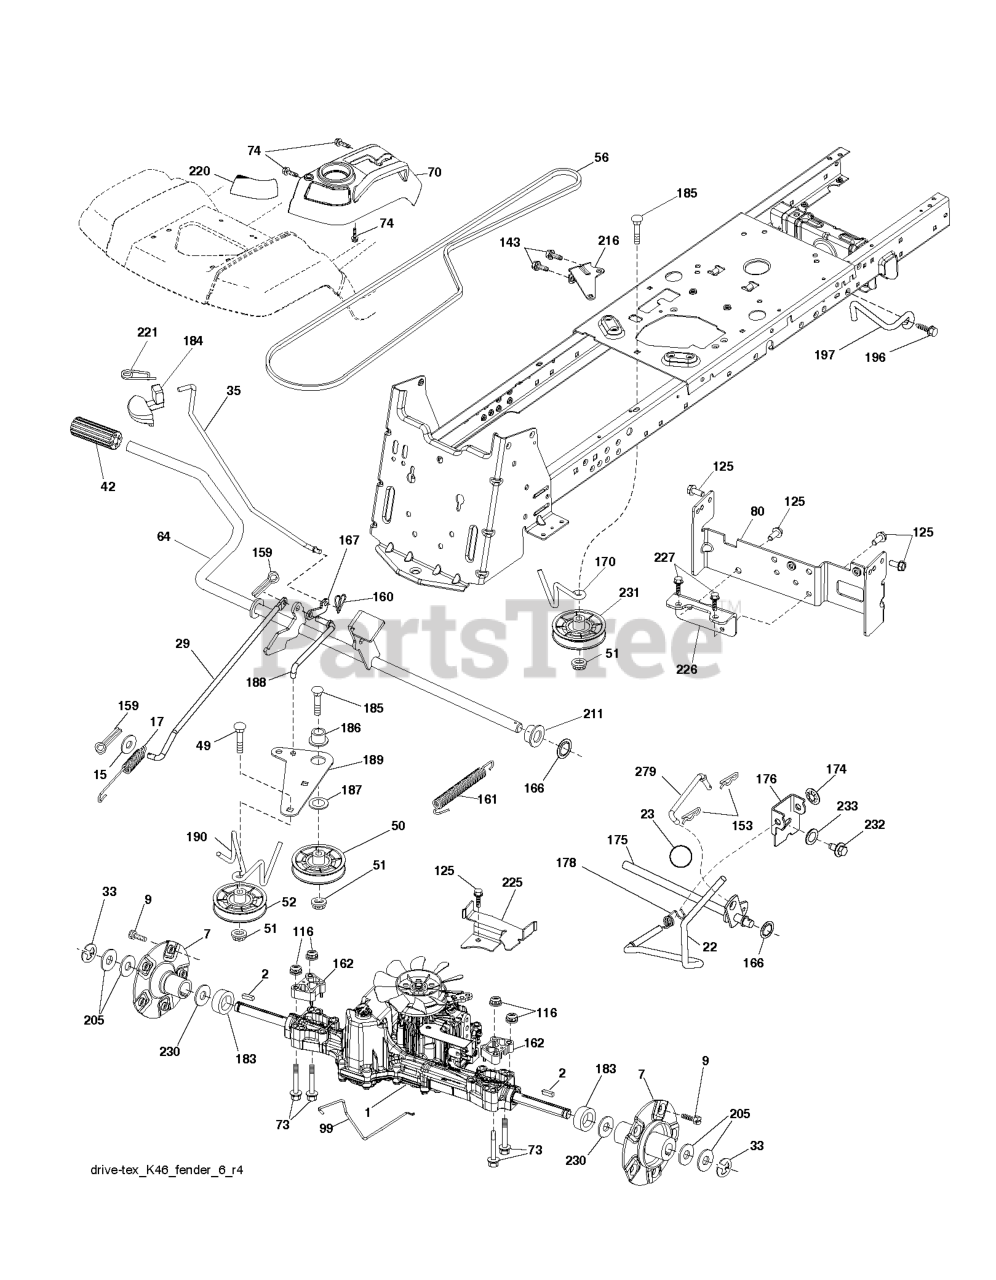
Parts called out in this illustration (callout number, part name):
2	KEY.SQUARE.187X2.500
7	HUB.ASM.WHEEL.REAR.22"
9	HUB BOLT
15	WASHER
17	SPRING.BRAKE.K46.GREEN
22	ROD.SHIFT.FENDER.STGT.
23	KNOB.DELUXE.(PISTOL.GRIP).BLAC
29	ROD.BRAKE.K46
35	ROD.BRAKE.PARTK.HUSQ.TEX
42	PEDAL COVER T
50	IDLER.FLAT.910.OFFSET
51	NUT LOCK FLG 3/8-16 UNC
52	IDLER.V-GROOVE.910.OFFSET
56	V-BELT.MOWER.92.40.42/K46
64	SHAFT.ASM.PEDAL.BRAKE.
70	SUBASM.CONSOLE.HUSQ.GT.HYDRO
73	BOLT.HEX.FLNG.5/16-18X3.75
74	SCREW.HI-LO.CONSOLE
80	STRAP.TORQUE.K46.K57R.TT
99	ROD.SPRING.BYPASS.K46.TEX.GT
116	NUT LOCK HEX FLANGE 5/16-18
125	SCREW
143	SCREW LT
153	RETAINER M
159	COTTER PIN
160	RETAINER CLIP
161	SPRING, RETURN LT
162	SPACER.TRANSAXLE.18&22
166	NUT.PUSH.625
167	LATCH.BRAKE.SPRING
170	KEEPER.CENTER SPAN.1.688
174	NUT.PUSH.500.2006
175	SHAFT ASM SHIFT
176	ARM.CLEVIS.ROD.SHIFT
178	SPRING.SHIFT.GT2006
183	SPACER.SPLIT.800X.350
184	RB HANDLE.PARKG.BRK.HUS/PRED
186	SPACER.RETAINER
187	WASHER 12/32X2X10GA
188	RP.LINK.CLUTCH.GROUND.DRIVE
189	BELLCRANK.GROUND.DRIVE.TEX.
190	KEEPER.BELLCRANK.DRIVE
196	SCREW 3/8-16X1
197	BRKT.ANIT-ROTATION.CLUTCH
211	BUSHING.SHAFT.BRAKE.HAND
216	BRACKET.PULLEY.IDLER.W/TEX
220	REFLECTOR.RH.TEX GT
221	RETAINER.SPRING.CLIP.H
225	KEEPER.BELT.TRANSAXLE.K46
226	BRKT.MOUNT.TORQUE.K46.
227	SCREW.THDROL.5/16-18X3/4.TTY
230	WASHER.HARDENED
231	IDLER.V-GROOVE.1.688.OFFSET
232	BOLT FIN HEX 7/16-14 X 1
233	WASHER SERRATED
279	LINK.SHIFT.T/A.K46.FEND.TX
